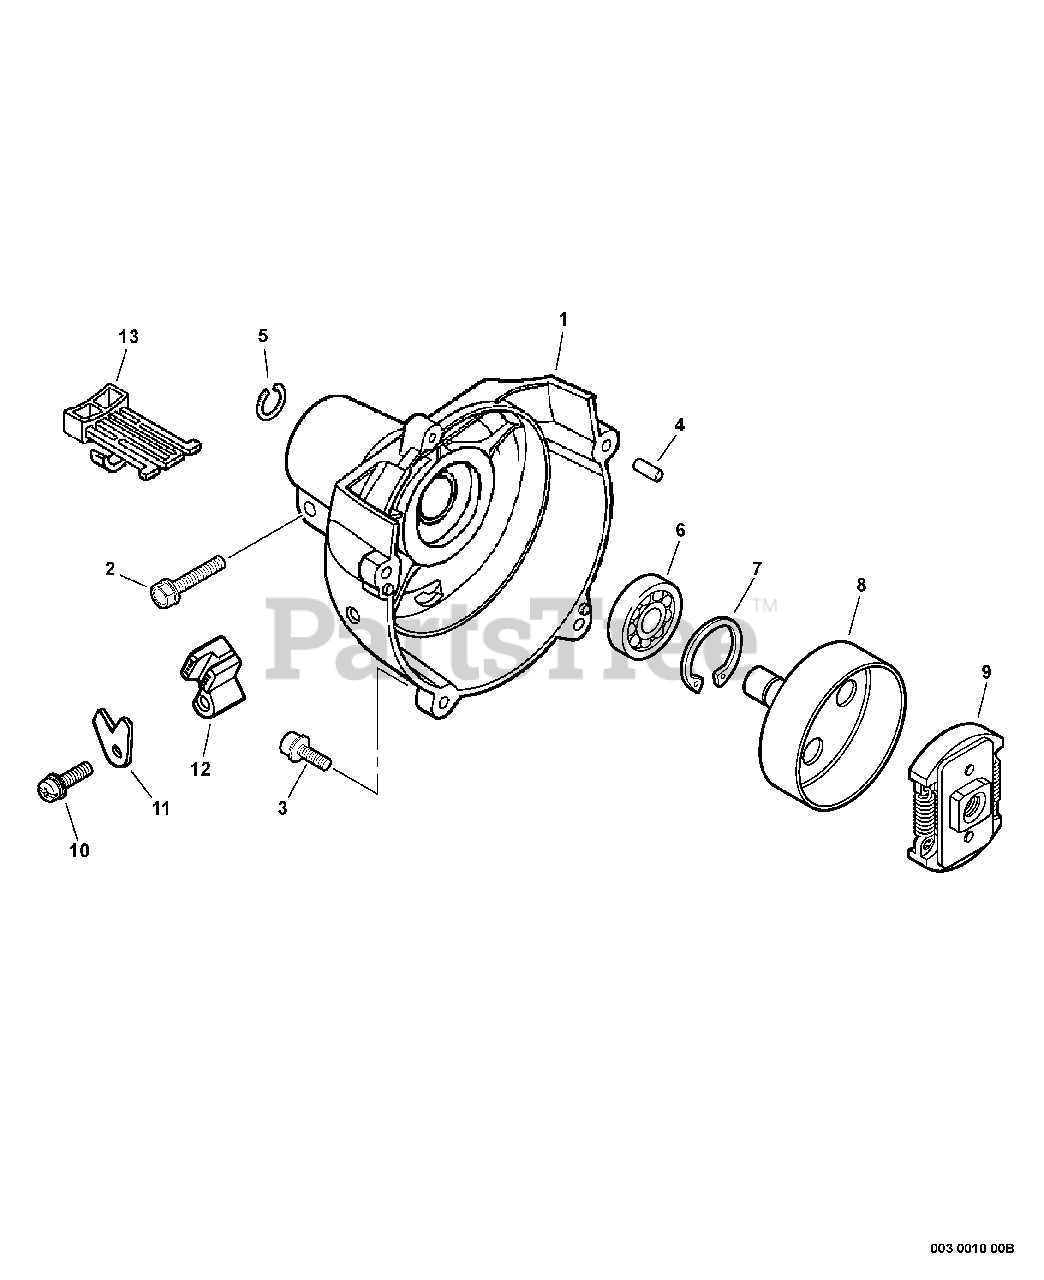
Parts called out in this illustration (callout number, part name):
1	COVER, FAN
2	BOLT 5×28
3	BOLT 4×16
4	PIN, LOCATING 4
5	RING, RETAINING - 12
6	BEARING, BALL 6201-ZZ
7	RING, SNAP Ø32
8	DRUM, CLUTCH
9	CLUTCH ASSY
10	SCREW 4×18
11	PLATE, EYE
12	HOLDER, CABLE
13	CLIP, CABLE
